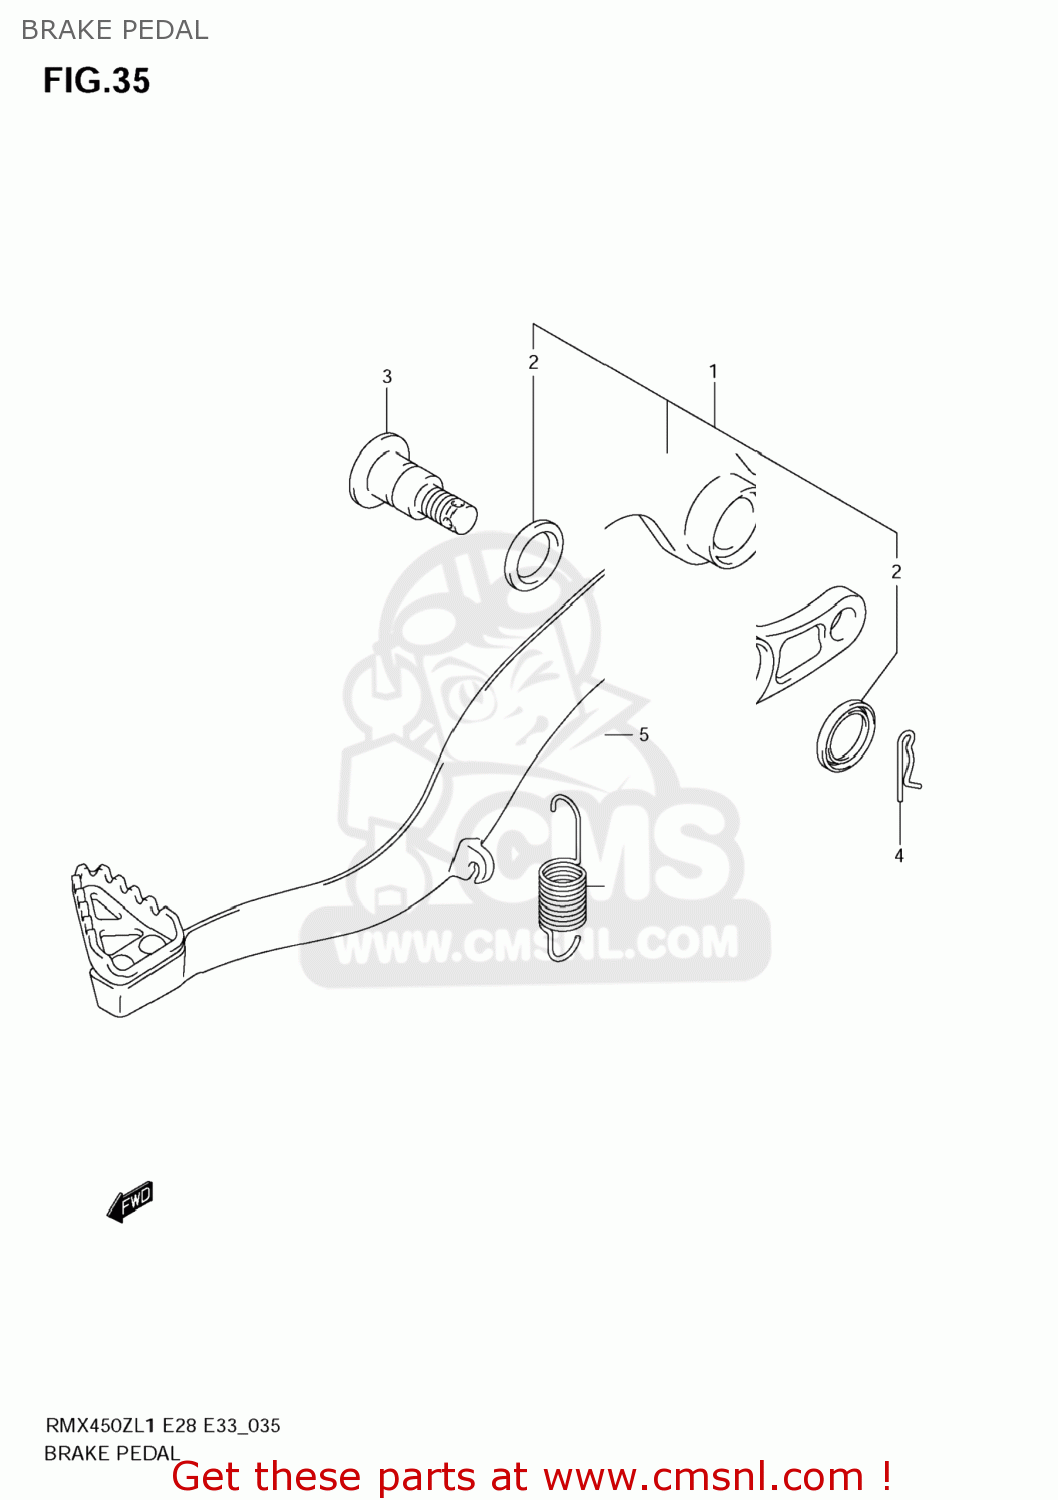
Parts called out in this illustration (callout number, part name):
1	PEDAL ASSY,BRAKE
2	SEAL,OIL(15X21X3)
3	SHAFT,BRAKE PEDAL
4	CLIP
5	SPRING
